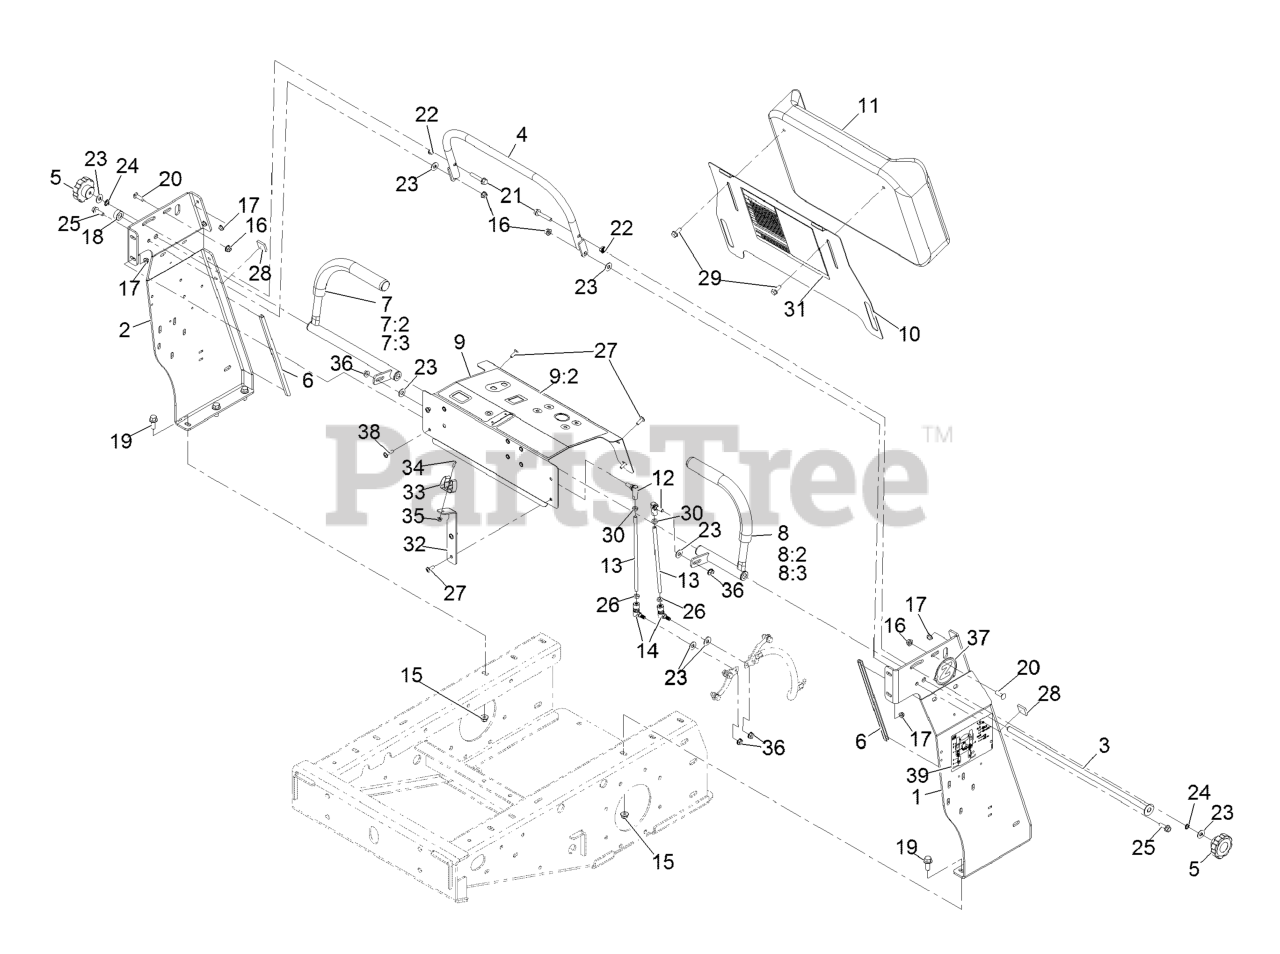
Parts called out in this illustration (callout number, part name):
1	Upright-Tower, Lt [blk-Txt]
2	Upright-Tower, Rt [blk-Txt]
3	Rod-Pivot, Joy Stick
4	Bar-Speed [blk-Txt]
5	KNOB-FLUTED
6	STRIP-TRIM, 12.0"
7	Stick-Joy, Rt
7:2	GRIP-CONTROL, MOTION
7:3	BUSHING-FLANGE
8	Stick-Joy, Lt
8:2	GRIP-CONTROL, MOTION
8:3	BUSHING-FLANGE
9	ASM-PANEL, CONTROL
9:2	Decal-Control Panel
10	PLATE-PAD, KNEE
11	PAD-KNEE, Z-LOGO
12	Balljoint-SS
13	ROD-CONTROL, MOTION
14	Ball Joint-Quick Disconnect, SS
15	Nut-Hex Flange
16	Nut-Hex Flange
17	Nut-Hex Flange
19	SCREW-HHF
20	Bolt,Carriage,5/16-18X1,ST/ST 18-8
21	Screw-HHF
22	Nut,Hex Flange,5/16-18,Sst, Rie2006
23	FLAT WASHER, 5/16 NOM,ST
24	Washer-Lock
25	SCREW-HHF
26	Nut-Hex
27	Screw-Hsbhf
29	SCREW-HHF
30	Nut-Hex
31	Decal-Spray Chart
32	Mount-Gun
33	Holder-Tool, Clip
34	Screw-HSBH
35	Nut-Hex Flange
36	Nut-HHF
37	Decal-Z-Logo
38	Screw-Hsbhf
39	Decal-Service Aid
